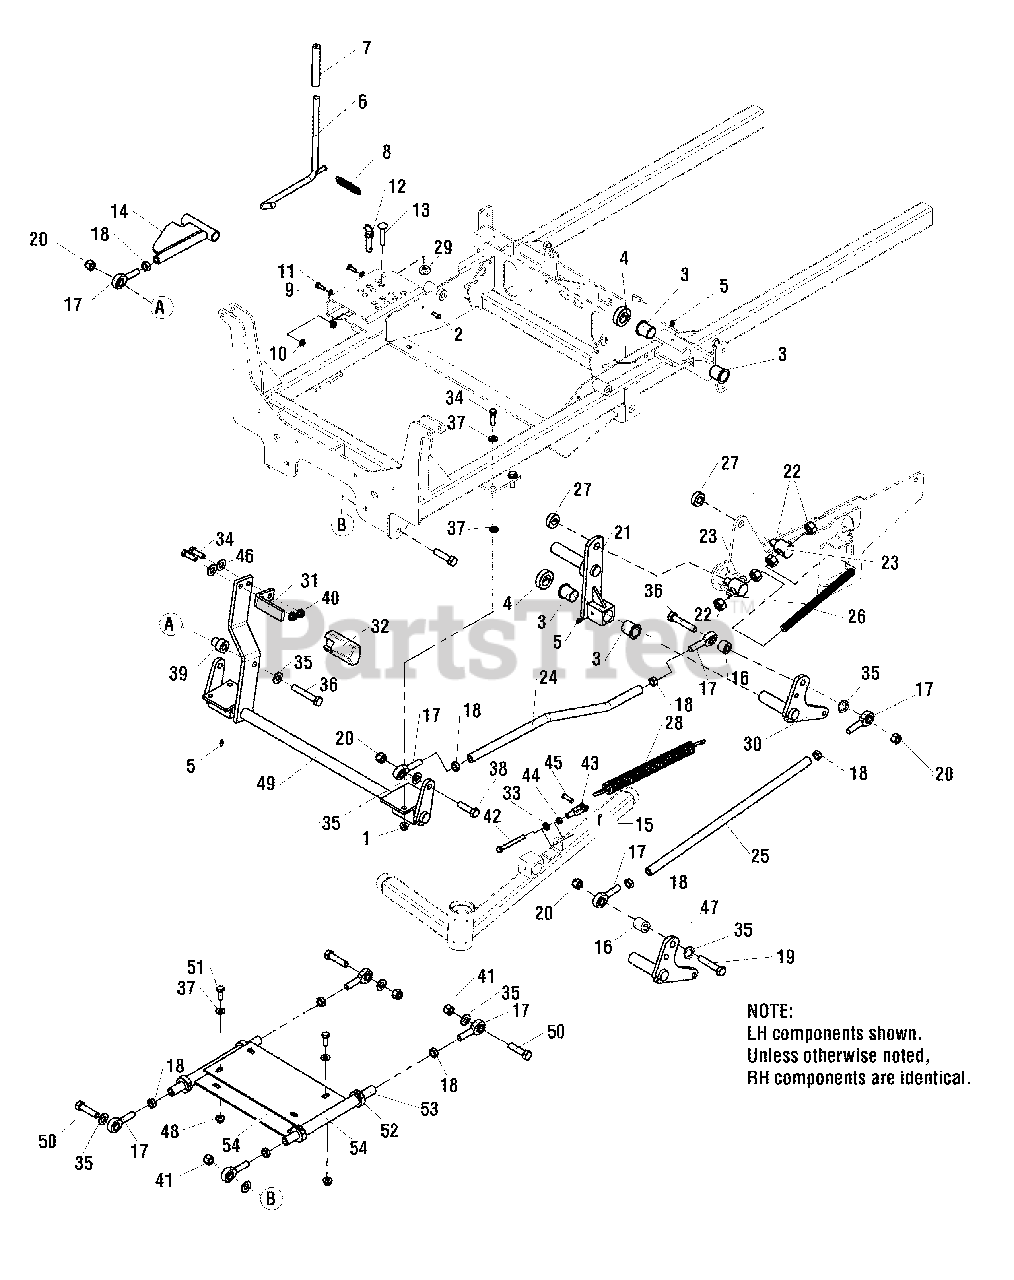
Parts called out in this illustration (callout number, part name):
1	NUT, 3/8-16 HEX NYLOCK FLANGE
2	PIN, CLEVIS, 1/4" x 3/4"
3	BUSHING, 1.00 X 1.13 X 1.38, PLASTIC
4	COLLAR, 1" SPLIT
5	GREASE FITTING, 1/4-28 STR
6	WELD, ROD DECK LIFT - BLK
8	SPRING, EXTENSION
9	WASHER, 1/4 SAE (5025154)
10	NUT, 1/4-20 HEX SERR. FLANGE
11	BOLT, 1/4-20 X 3/4" GD5
12	HITCH PIN, 1/2 X 2"
13	CARRIAGE BOLT, 3/8-16 X 2"
14	WELD, DECK ADJUST LINK - ORANGE
15	PIN, COTTER, 3/32" X 3/4
16	SPACER, .52 X 1.00 X .75
17	BALL JOINT, 1/2-20, MALE
18	NUT, 1/2-20 HEX JAM
19	BOLT, 1/2-13 X 2-3/4" GD5
20	NUT, 1/2-13 HEX NYLON LOCK
21	WELD, REAR LIFT - LH - ORANGE
22	NUT, 5/8-11 HEX
23	PIVOT, SPRING ROD
24	ROD, DECK LIFT BENT
25	ROD, DECK LIFT, OUTER
26	ROD, 5/8-11 X 9.00
27	COLLAR, 5/8" SPLIT
28	SPRING, DECK LIFT ASSIST
29	NUT, 3/8-16 HEX SIDE LOCK
30	WELD, DECK LIFT LEVER, LH - ORANGE
31	PEDAL, FOOT - BLK
32	RUBBER, FOOT PEDAL
33	WASHER, 5/16" GD.9 FLAT
34	BOLT, 3/8-16 X 1-1/4" GD5
35	WASHER, 1/2" GD9 YZ
36	BOLT, 1/2-13 X 3-1/2" GD5
37	WASHER 3/8" SAE
38	BOLT, 1/2-13 X 1-3/4" GD5 YZ
39	ADAPTER, CASTER AXLE
40	NUT, 3/8"-16 HEX NYLON LOCK
41	NUT, 1/2-20 HEX NYLON LOCK
42	BOLT, 5/16-18 X 3", FLT
43	CLEVIS, 5/16-18, 5/16" PIN HOLE, STEEL
44	NUT, 5/16-18 HEX
45	PIN, CLEVIS 5/16" X 1"
46	WASHER, 3/8" GR9 FLAT
47	WELD, DECK LIFT PIVOT, LH - ORANGE
48	NUT, 3/8-16 HEX SERRATED FLANGE
49	WELD, DECK LIFT SHAFT
50	BOLT, 1/2-20 X 1-3/4" GD5 YZ
51	BOLT, 3/8-16 X 1" GD5
52	COLLAR, 3/4" SPLIT
53	SHAFT, DECK STABILIZER
54	WELD, DECK STABILIZER - BLK
